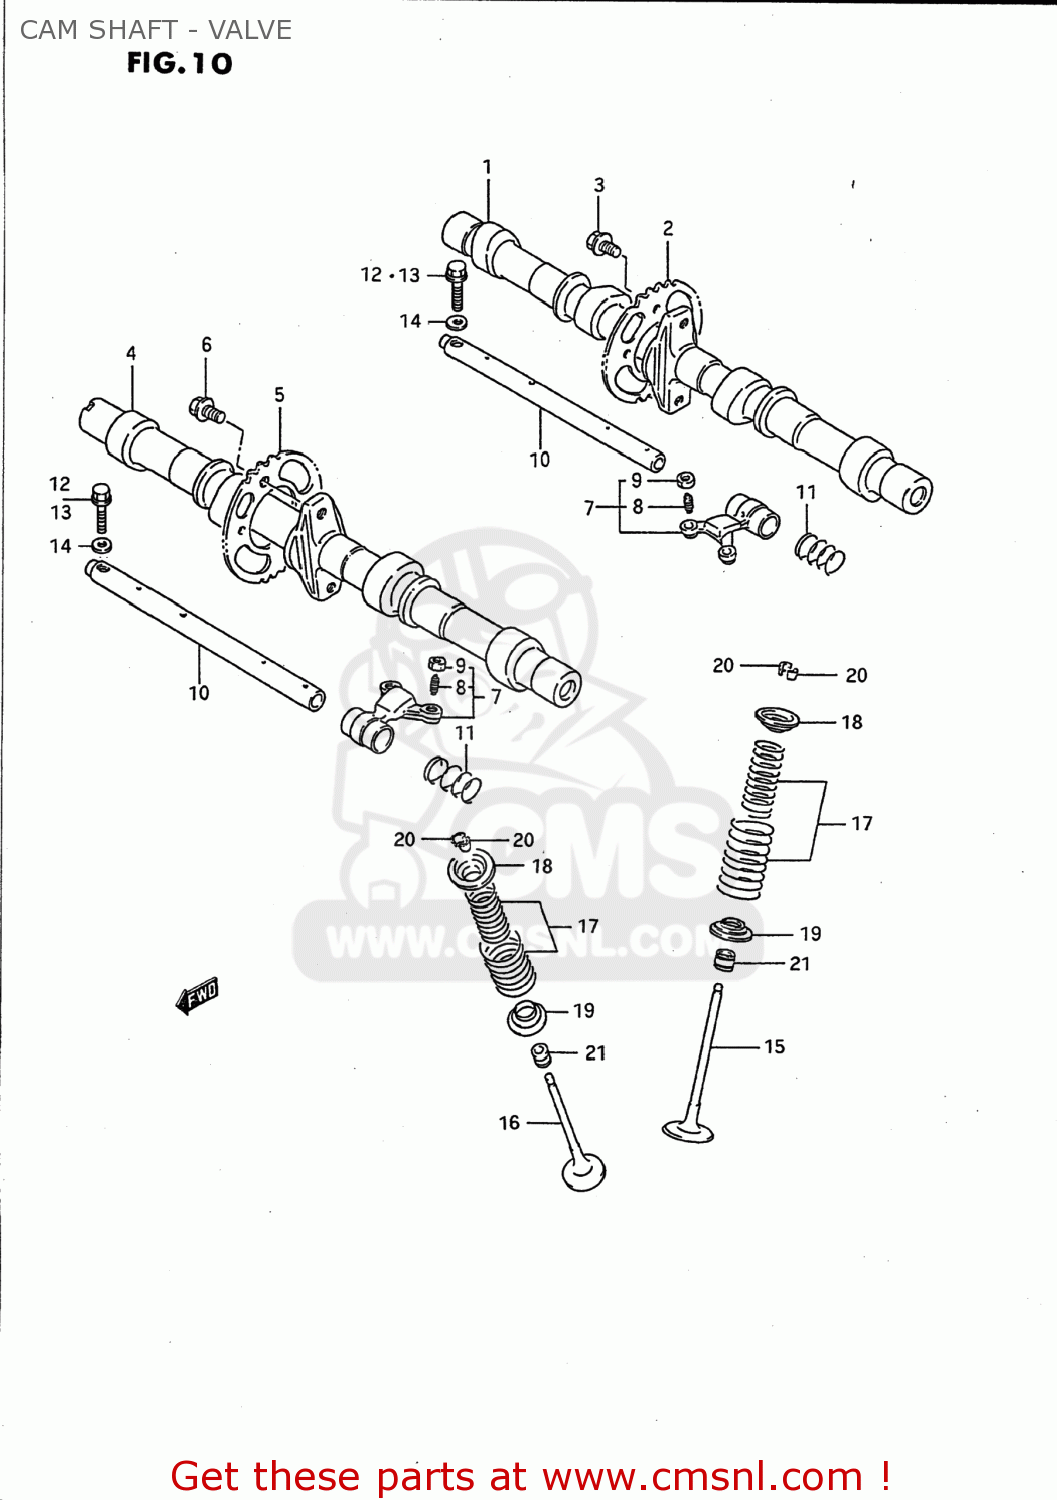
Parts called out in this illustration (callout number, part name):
1	CAMSHAFT,INTAKE
2	SPROCKET,CAMSHAFT
3	BOLT(7X11)
4	CAMSHAFT,EXHAUST
5	SPROCKET,CAMSHAFT
6	BOLT(7X11)
7	ARM,VALVE ROCKER
8	SCREW,TAPPET ADJUSTING
9	NUT,TAPPET ADJUSTING
10	SHAFT,VALVE ROCKER ARM
11	SPRING
12	BOLT
13	BOLT
14	WASHER
15	VALVE,INTAKE
16	VALVE,EXHAUST
17	SPRING SET,VALVE
18	RETAINER,VALVE SPRING
19	SEAT,VALVE SPRING
20	COTTER VALVE
21	SEAL,OIL(5X10X9.7)
